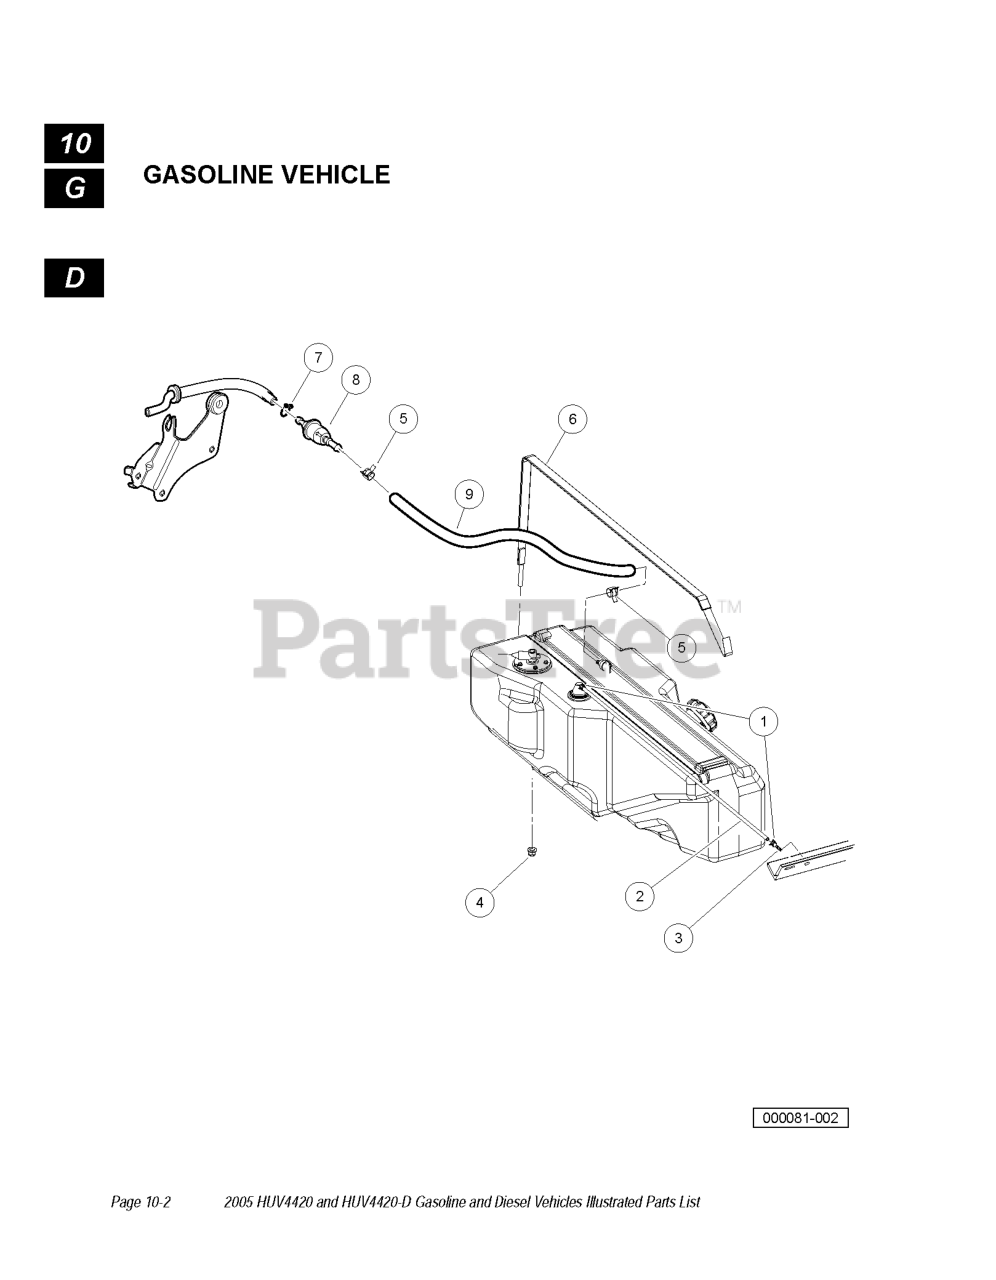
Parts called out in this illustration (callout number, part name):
2	TUBE, CARBURETOR AIR VENT
4	NUT FLG, M8 X 1.25 MECH DEF
5	CLAMP, HOSE, CTB 13MM
6	STRAP, TANK, FUEL
7	CLIP, TUBE, B10
8	FILTER FUEL
9	HOSE, TANK TO FILTER, FH680D
